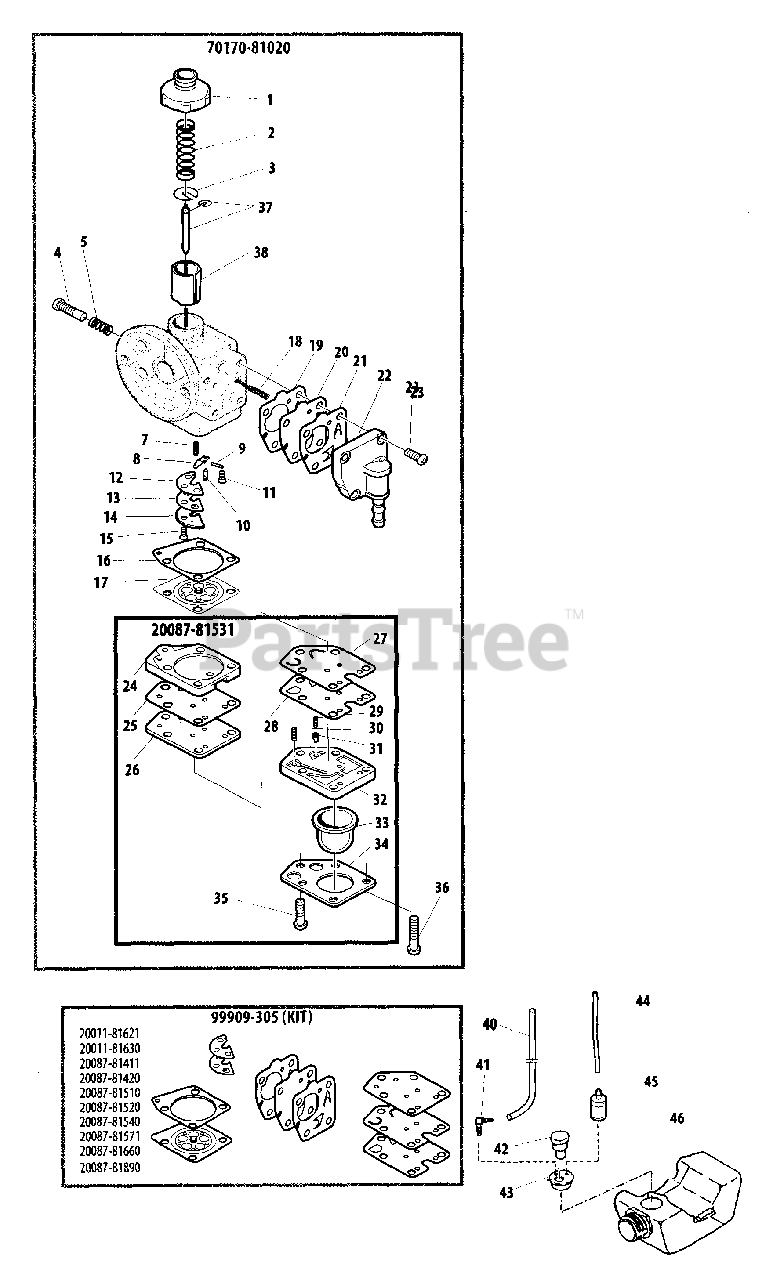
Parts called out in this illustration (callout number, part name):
1	CAP, CARBURETOR
2	SPRING
3	WASHER, SPRING SUPPORT
4	SCREW, IDLE ADJUST
5	SPRING
7	SPRING
8	LEVER, METERING
9	PIN, METERING LEVER
10	VALVE, INLET NEEDLE
11	SCREW M3×8
12	GASKET
13	VALVE, CHECK
14	PLATE
15	SCREW M3×8
16	GASKET, METERING DIAPHRAGM
17	DIAPHRAGM, METERING
18	SPRING, COIL
19	GASKET, DIAPHRAGM
20	DIAPHRAGM, METERING
21	VALVE, PUMP
22	PUMP BODY
23	SCREW
24	COVER, PUMP
25	GASKET
26	PLATE, PUMP
27	VALVE, CHECK
28	GASKET
29	SPRING
30	SPRING
31	VALVE, CHECK
32	COVER, PUMP
33	BULB, PURGE
34	RETAINER, PURGE BULB
35	SCREW
36	SCREW 3×20
37	NEEDLE, JET
38	SLIDE VALVE
40	PIPE, RETURN
41	CONNECTOR, PIPE
42	VENT ASSY
43	GROMMET, FUEL TANK
44	PIPE, FUEL
45	FILTER, FUEL
46	TANK, FUEL
